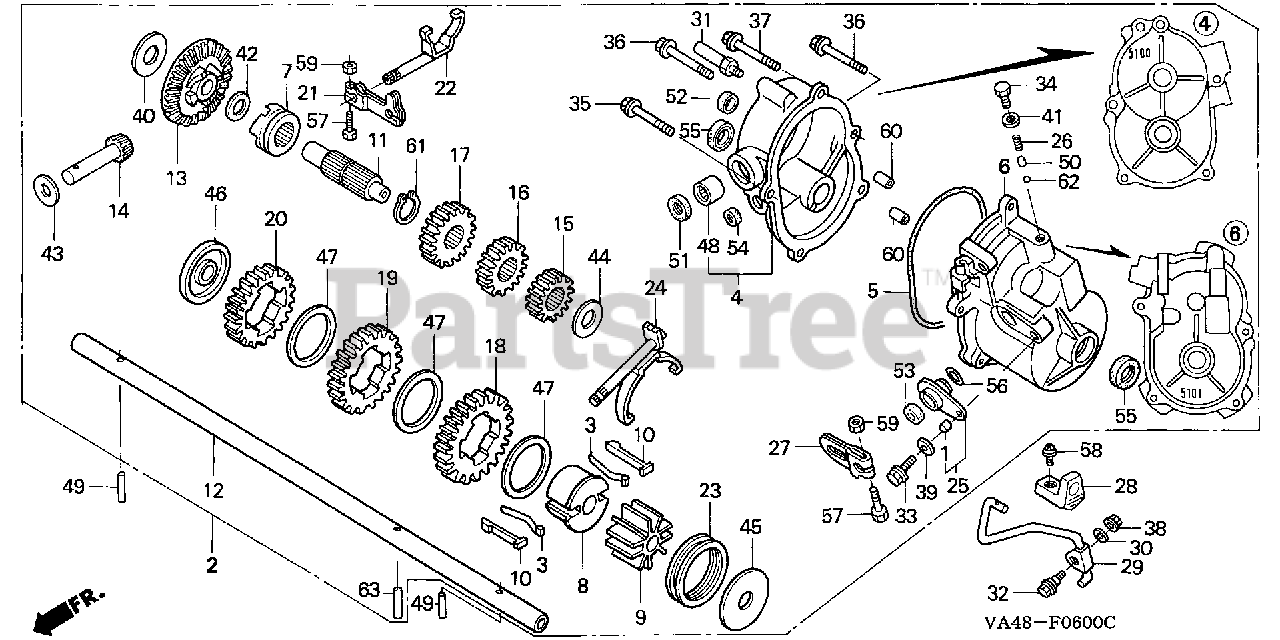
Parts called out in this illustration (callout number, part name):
1	COLLAR, FAN
2	TRANSMISSION ASSY. (DANA CORP.)
3	SPRING, CHANGE KEY
4	CASE, R. TRANSMISSION (NOT AVAILABLE)
5	O-RING, TRANSMISSION CASE
6	CASE, L. TRANSMISSION
7	CLUTCH, DRIVEN
8	BOSS, CHANGE SHAFT
9	HOLDER, KEY
10	KEY, CHANGE SHAFT
11	COUNTERSHAFT
12	SHAFT, FINAL
13	GEAR, BEVEL (44T)
14	PINION, BEVEL
15	GEAR, FIRST DRIVE (14T)
16	GEAR, SECOND DRIVE (18T)
17	GEAR, THIRD DRIVE (20T)
18	GEAR, FIRST DRIVEN (33T)
19	GEAR, SECOND DRIVEN (29T)
20	GEAR, THIRD DRIVEN (27T)
21	ARM, CLUTCH
22	SHAFT, SHIFT
23	SHIFTER
24	FORK, SHIFT
25	GUIDE, CHANGE LEVER
26	SPRING, BALL SETTING
27	ARM, CHANGE
28	KNOB, CHANGE LEVER
29	LEVER, CHANGE
30	PLATE, ADJUSTING
31	BOLT, GUIDE (8MM)
32	BOLT, TANK SETTING
33	BOLT, FLANGE (6X16)
34	BOLT, HEX. (8X10)
35	BOLT, FLANGE (6X35)
36	BOLT, FLANGE (6X25)
37	BOLT, FLANGE (6X25)
38	NUT, NYLON RING (6MM)
39	WASHER, PLAIN (6.5X15)
40	WASHER, THRUST (14X32X1)
41	WASHER, SEALING (8X16X1.6)
42	WASHER (14MM)
43	WASHER (10X21)
44	WASHER B, THRUST (12MM) (1.0)
45	WASHER, THRUST (15X45X1.5)
45	WASHER, THRUST (15X45)
46	WASHER, SPECIAL (15MM)
47	WASHER (35X45X1)
48	BEARING, NEEDLE (10X17X20)
49	ROLLER (5X23.8)
50	RETAINER, BALL (6MM)
51	OIL SEAL (10X17X4)
52	PLUG, SEALING (14X4)
53	OIL SEAL (8X16X6)
54	OIL SEAL (8X14X5)
55	OIL SEAL (15X24X5)
56	O-RING (12.3X1.9)
57	BOLT, HEX. (5X20)
58	SCREW-WASHER (4X12)
59	NUT, HEX. (5MM)
60	PIN A, DOWEL (8X14)
61	CIRCLIP (OUTER) (18MM)
62	BALL, STEEL (#6) (3/16)
63	ROLLER (6X22.4)
